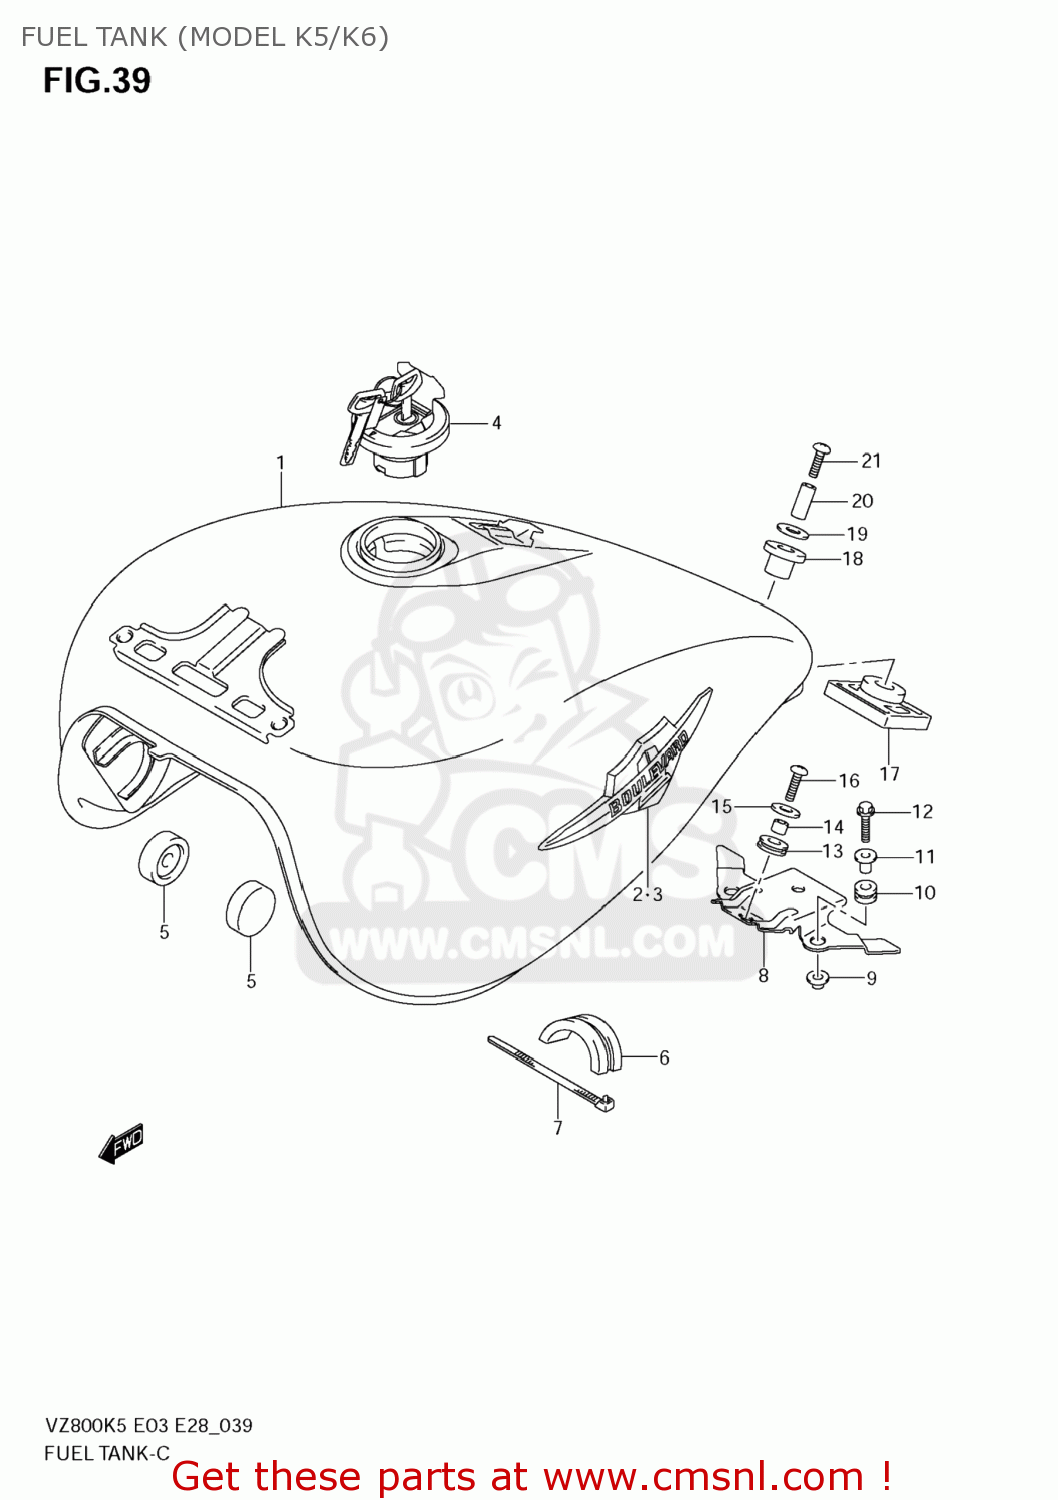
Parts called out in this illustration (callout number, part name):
1	TANK ASSY,FUEL(RED)
2	EMBLEM,FUEL TA
3	EMBLEM,FUEL TA
4	CAP SET,FUEL TANK
5	CUSHION
6	CUSHION,FUEL TANK LWR
7	CLAMP(L:250)
8	BRACKET COMP,F
9	WASHER
10	CUSHION
11	WASHER
12	SCREW
13	CUSHION
14	SPACER(8.5X12X7.5)
15	WASHER (8.5X26X1.6)
16	BOLT(8X20)
17	CUSHION,FUEL TANK RR LWR
18	CUSHION,FUEL TANK RR UPR
19	SPACER (8.2X12.5X23.5)
20	WASHER (8.5X33X1.6)
21	BOLT
